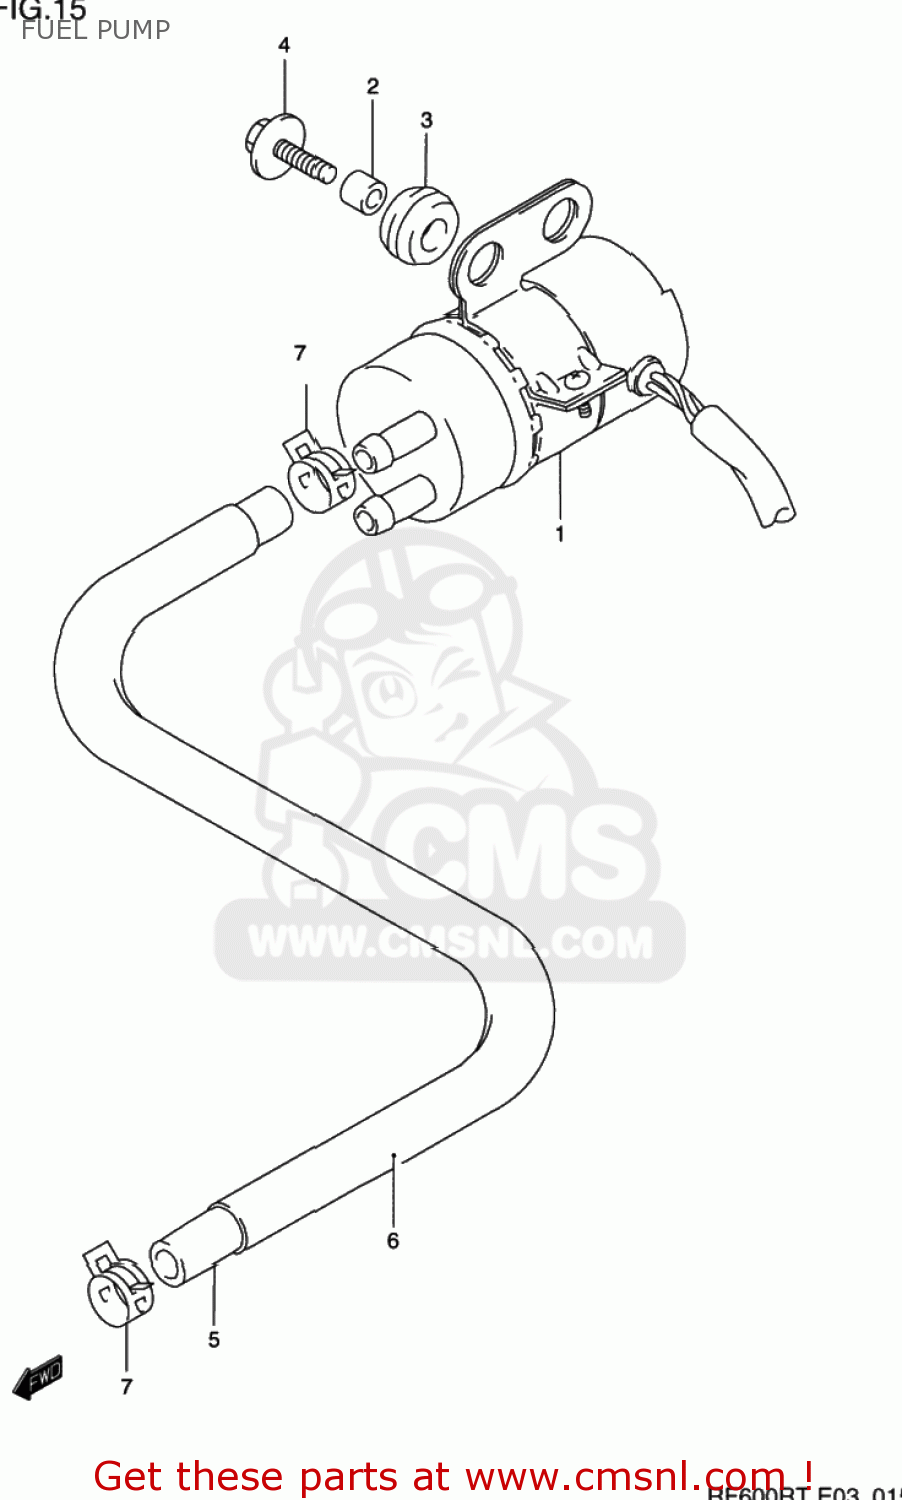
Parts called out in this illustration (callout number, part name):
1	PUMP ASSY,FUEL
2	SPACER (6.1X9X9)
3	CUSHION
4	BOLT(6X20)
5	HOSE (7X13X600)
6	PROTECTOR(14.5X15.5X600)
7	CLIP
